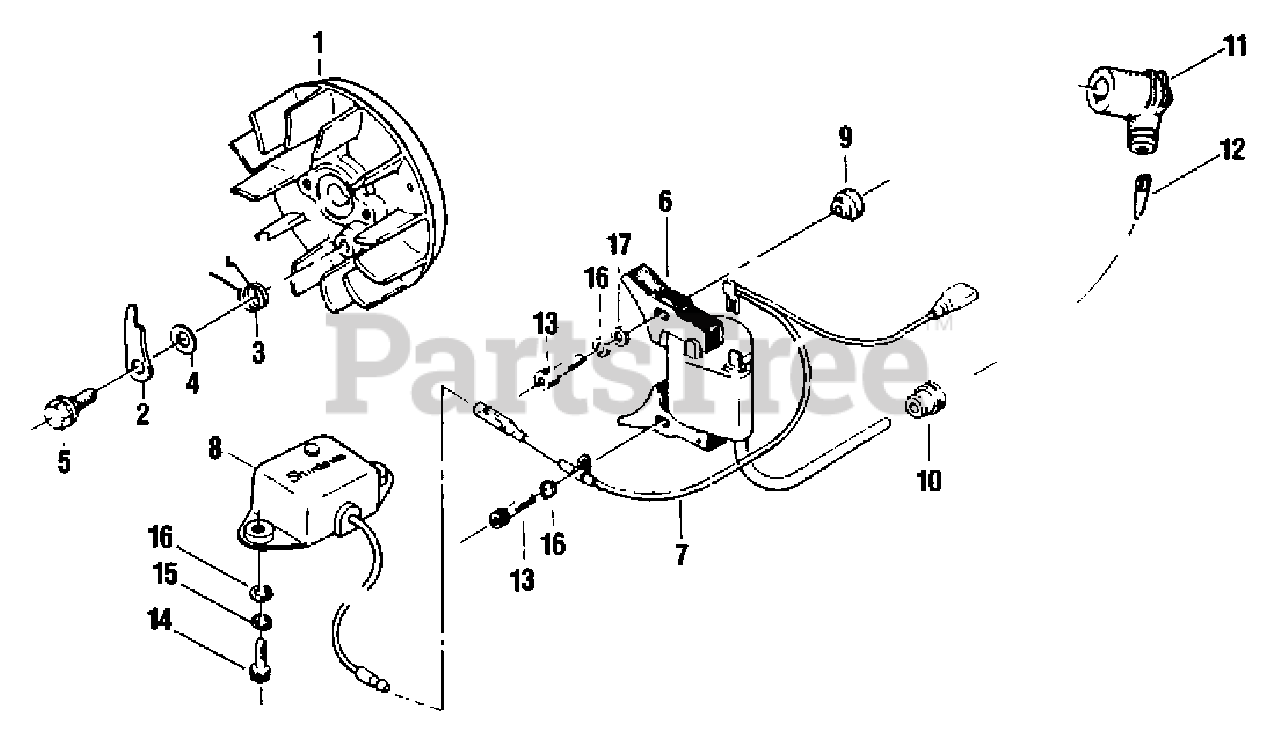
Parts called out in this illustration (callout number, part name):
1	ROTOR
2	RATCHET
3	SPRING, RATCHET
4	WASHER 6 MM
5	BOLT
6	COIL
7	WIRE, LEAD
8	UNIT
9	COLLAR 4
11	CAP, SPARK PLUG
12	TERMINAL, SPARK PLUG
13	BOLT M4×24
14	BOLT 4×10
15	WASHER, SPRING 4 MM
16	WASHER 4 MM
